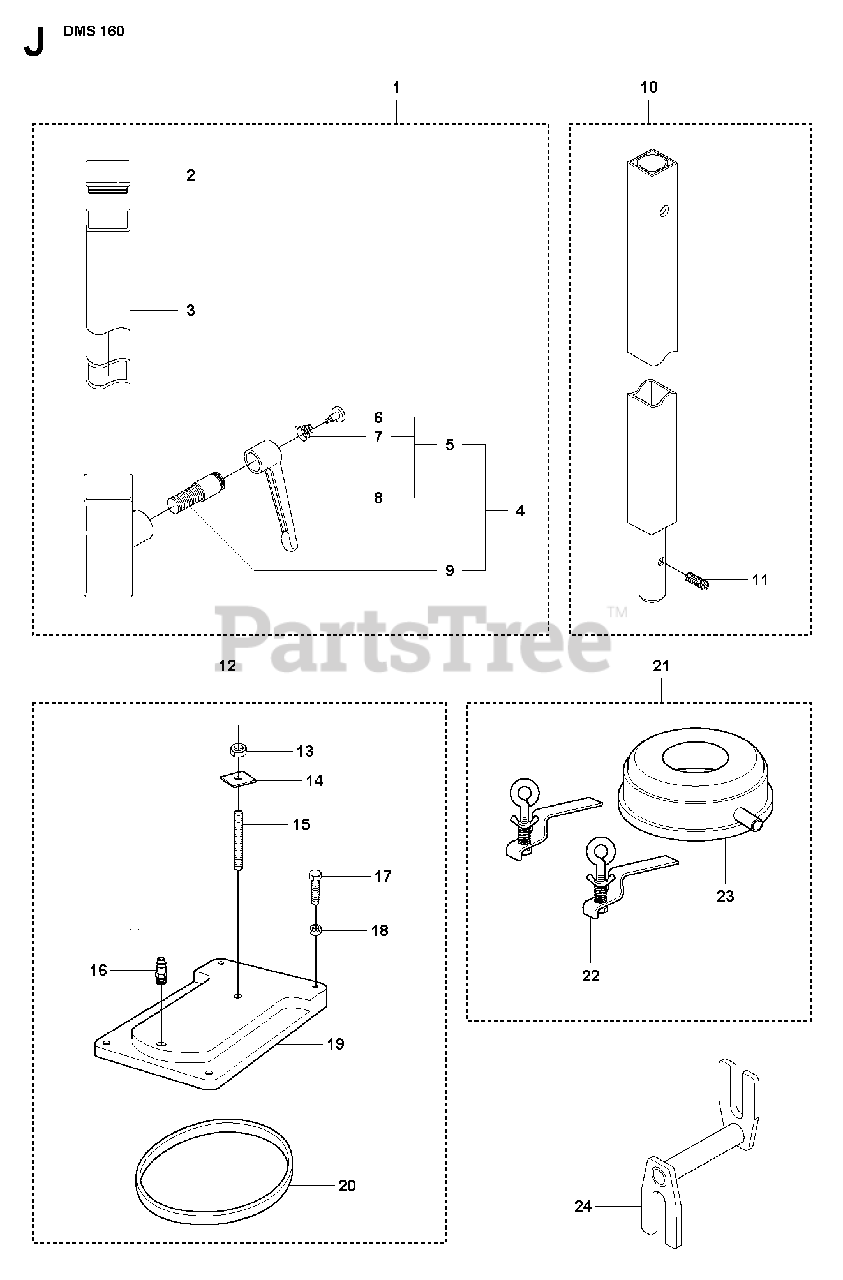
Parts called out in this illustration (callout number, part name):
5	HANDLEIncl. 6-8
12	VACUUM PLATEIncl. 13-20
21	COLLECTORIncl. 22, 23
